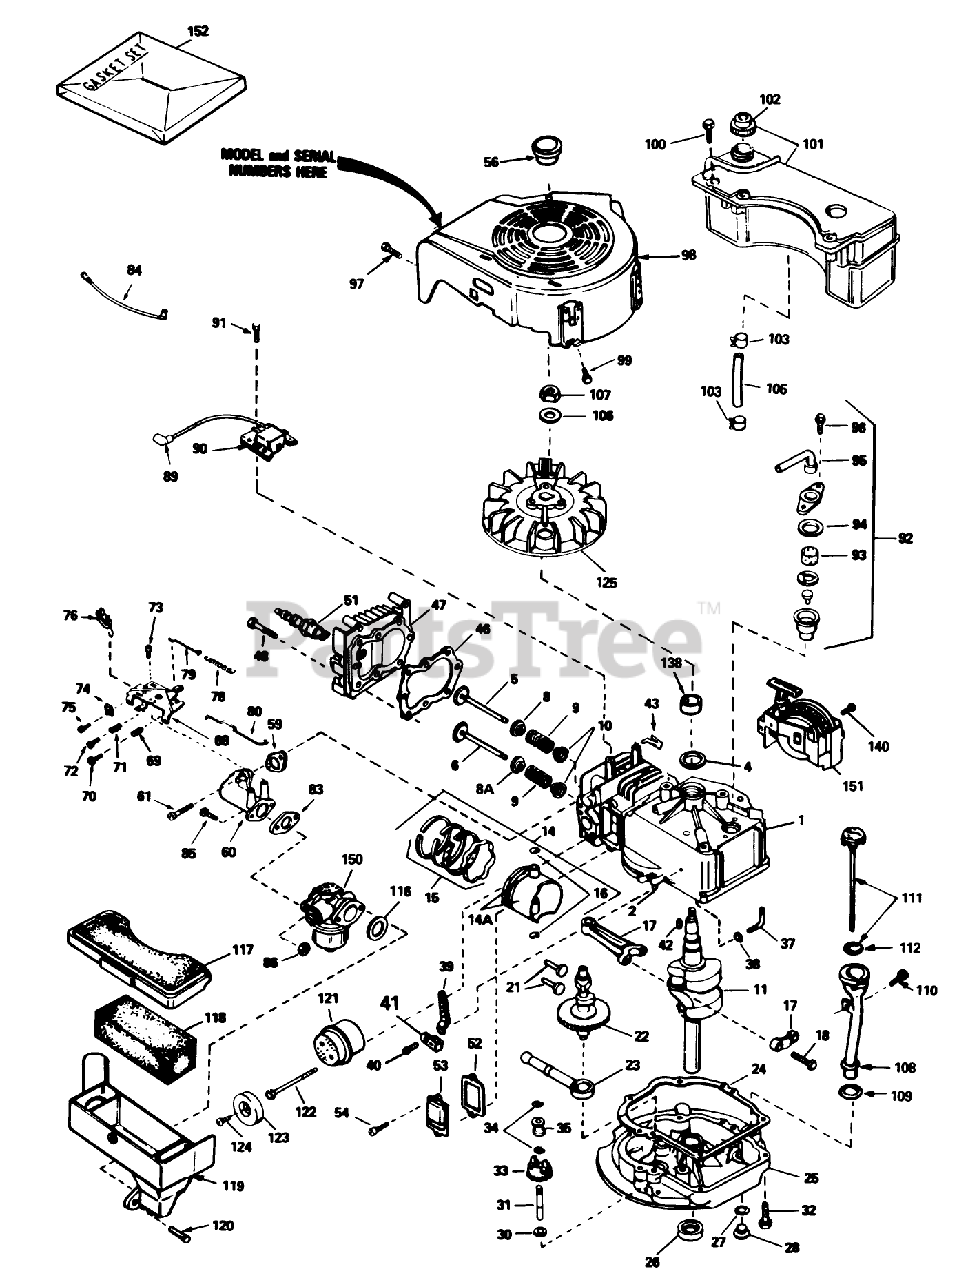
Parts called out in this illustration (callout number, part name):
1	Cylinder Assy. (Incl. #24)
2	Pin-Dowel
4	Seal-Oil
5	Valve, Intake (Std.) (Incl. Ref. #40)
5	Valve, Intake (1/32" oversize)(Incl. No. 40)
6	Valve, Exhaust (Std.)(Incl. No. 40)
6	Valve, Intake (1/32" oversize)(Incl. No. 40)
8	Seal Assy., Intake
8A	Cap-Upper Valve Spring
9	Spring-Valve
10	Cap-Valve, Spring
11	Crankshaft
14	Piston, Pin Ring Assy. (Std.) (Incl. Ref. #13A, 14 15)
14	Piston, Pin Ring Assy. (.010 oversize) (Incl. Ref. #13A, 14 15)
14	Piston, Pin Ring Assy. (.020 oversize) (Incl. Ref. #13A, 14 15)
14A	Piston Pin Assy. (Incl . Ref. . #14) (Std.)
14A	Piston Pin Assy. (Incl. Ref. #14) (.010 Oversize)
14A	Piston Pin Assy. (.020 oversize) (Incl. Ref. #14)
15	Ring Set (Std.)
15	Ring Set (.020" OS)
15	Ring Set (.010" OS)
16	Ring-Retaining, Piston Pin
17	Rod Assy., Connecting (Incl. Ref. #17)
18	Bolt-Rod, Connecting
21	Lifter-Valve
22	Camshaft(Mech.Comp. Release)
23	Oil Pump ASM
24	Gasket
25	Flange Assy.-Mounting (Incl. Ref. #26, 27, 28 31)
26	Seal Oil
27	Gasket-Oil Drain
28	Plug Oil Drain
30	Washer-Flat
31	Shaft-Governor
32	Screw (1/4-20 x 1-1/4)
33	Governor Gear ASM
34	Ring-Retaining
35	Spool-Governor
37	Rod, Governor (Incl. No. 36)
38	Washer-Flat
39	Governor Lever
40	Screw
41	Clamp-Lever, Governor
42	Key-Flywheel
46	63573 GIL 42 SNWTHW
47	Head-Cylinder
48	Screw (5/16-18x1-1/2)
51	Plug, Spark (J17LM or equiv.)
51	Plug, Spark (Champion RCJ-8)
52	Gasket-Breather
53	Cover-Valve
54	Screw
56	Plug, Screen
59	Gasket-Intake
60	Pipe-Intake (Incl. Ref. #59)
61	Screw (1/4-20 x 1)
68	Control Assy.-Remote Speed (Incl. Ref. #69 thru 72 76)
69	61709/GIL1515A/95-5
70	Screw
71	Spring-Compression
72	Screw
73	Screw (10-24 x 9/16)
74	Conduit
75	Screw (10-32 x 3/8)
76	Terminal
78	Spring Governor
79	2035A67 ADD.ASSEMBL
80	Link-Throttle
83	Gasket
84	Wire-Ground
86	Nut and Lock Washer (1/4-28)
89	Cover-Spark Plug
90	Solid State
91	Screw
92	Breather Assy. (Incl. Ref. #46 thru 51)
93	Element-Breather
94	Gasket-Breather
95	Tube, Breaker
96	Screw (10-24 x 9/16)
97	Screw (10-24 x 9/16)
98	Housing-Blower
99	Screw (1/4-20 x 1/2)
100	Screw (10-32 x 35/64)
101	Tank Assembly-Fuel (Incl. Ref. #102)
102	Cap-Fuel
103	Clamp-Line, Fuel
105	Line-Fuel
106	Washer-Belleville
107	Nut-Flywheel
108	Tube-Oil Fill
109	Gasket
110	Screw (10-32 x 1/2)
111	Dipstick-Oil (Incl. Ref. #112)
112	O-Ring
116	Gasket-Cleaner, Air
117	Cover Air Cleaner
118	Filter-Air Cleaner
119	Body Air cleaner
120	Screw
121	Muffler (Incl. Ref. #122)
122	Screw
123	Cover-Muffler
124	Screw
125	Flywheel
138	Spacer
140	Screw (1/2-20x5/8)
150	Carburetor (Incl. Ref. #83)
151	Starter-Sidemount
152	Gasket Set
